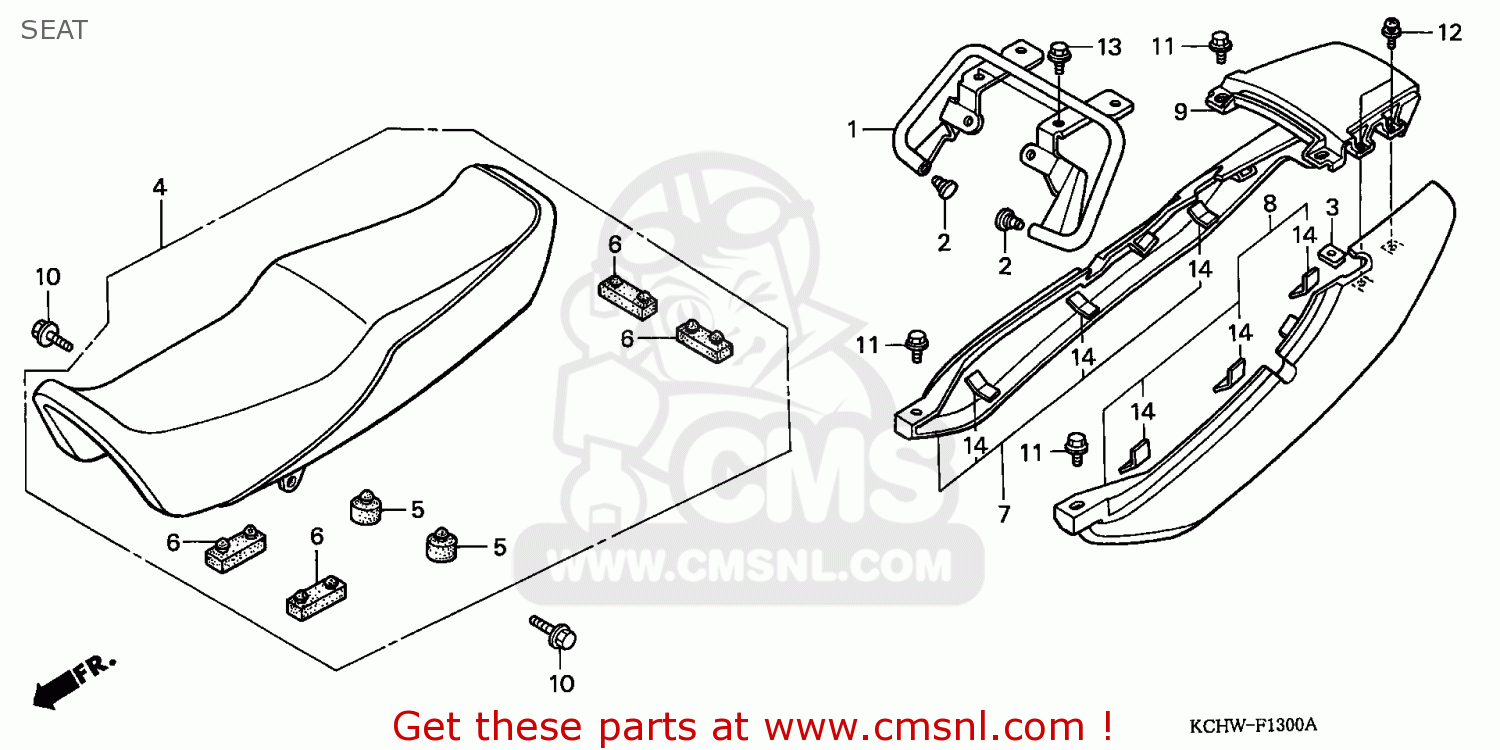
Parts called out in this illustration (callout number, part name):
1	PIPE COMP,REAR GR
2	PLUG,STEP BAR
3	NUT,CLIP,4MM
4	SEAT ASSY,DOUBLE
5	RUBBER A,SEAT
6	RUBBER B SEAT
7	REAR COWL,*PB162*
8	REAR COWL,*PB162*
9	SET ILLUST*PB162*
10	BOLT,SEAT SETTING
11	BOLT,SPECIAL,6X19
12	SCREW-WASH,4MM
13	BOLT,FLANGE,6X12
14	CUSHION,BATT.B
